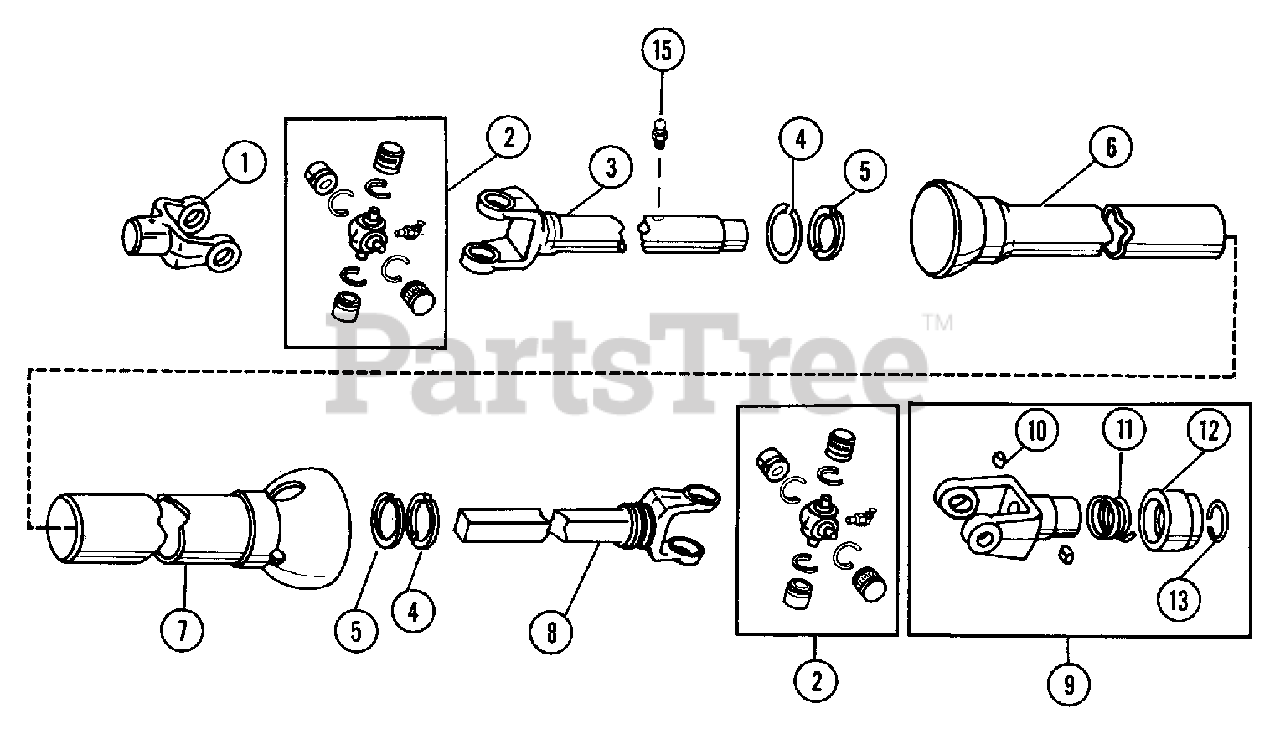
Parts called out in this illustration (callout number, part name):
1	END YOKE
2	REPAIR KIT
3	YOKE AND TUBE
4	RG-RTNG WEASLER #2A N20
5	BRG-BALL NYL WEASLER
6	MALE GUARD TUBE
7	FEMALE GUARD TUBE W/DECAL
8	YOKE AND SHAFT
9	LOCK YOKE ASSEMBLY
10	STAINLESS BALL
11	SG ??X??X?? WEASLER
13	RG-RTNG
15	ZERK FITTING
